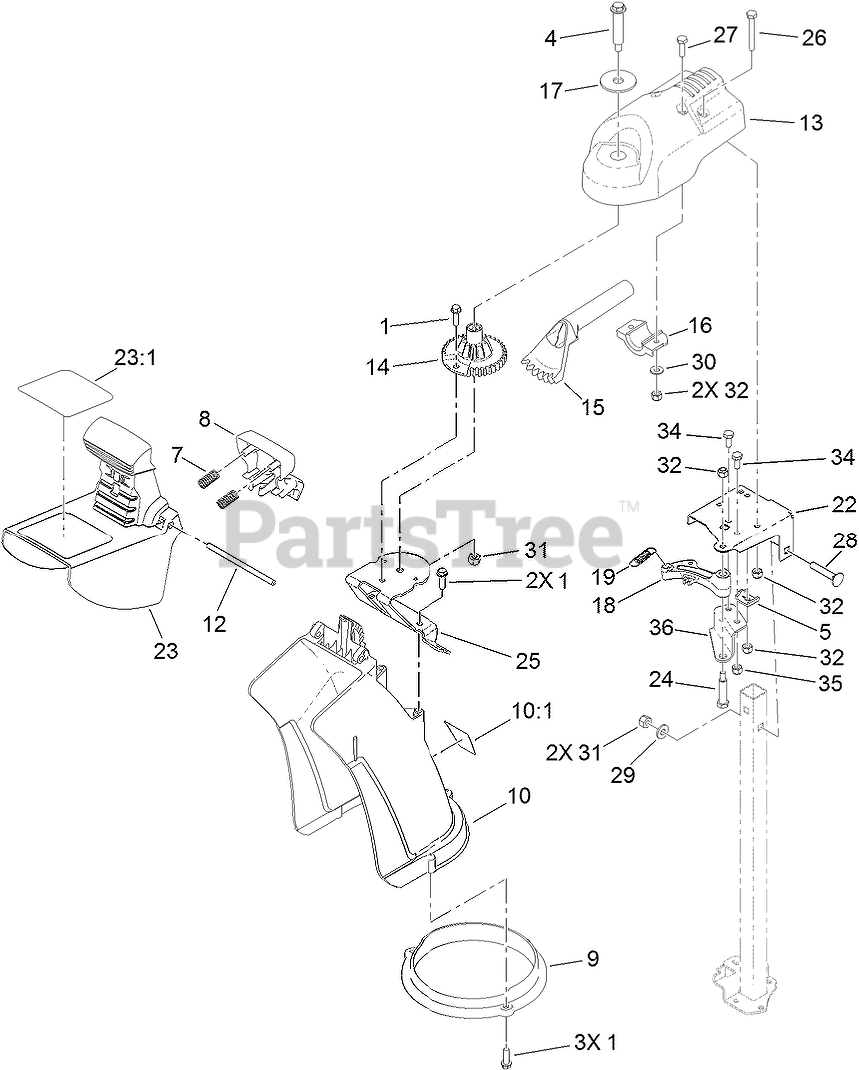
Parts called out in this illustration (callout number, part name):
1	SCREW-HWH
4	BOLT-SHOULDER
5	CLAMP-CABLE
7	SPRING-COMPRESSION
8	TRIGGER-DEFLECTOR
9	RING-CHUTE
10	CHUTE-DISCHARGE
10:1	DECAL-GUARANTEE
12	PIN-HINGE, DEFLECTOR
13	MOUNT-CHUTE, DISCHARGE
14	GEAR-CHUTE
15	GEAR-BEVEL
16	MOUNT-GEAR, BEVEL
17	WASHER-FLAT
18	LATCH-CHUTE
19	SPRING-LATCH, CHUTE
22	BRACKET-SUPPORT, CHUTE
23	DEFLECTOR-CHUTE
23:1	DECAL-DANGER
24	BOLT-SHOULDER
25	BRACKET-MOUNT, CHUTE
26	SCREW-HH
27	SCREW-HH
28	SCREW-CARR
29	WASHER-FLAT
30	WASHER-FLAT
31	NUT-LOCK, NI
32	NUT-LOCK, NI
34	SCREW-HH
35	NUT-LOCK, NI
36	BRACKET-SUPPORT, LATCH
